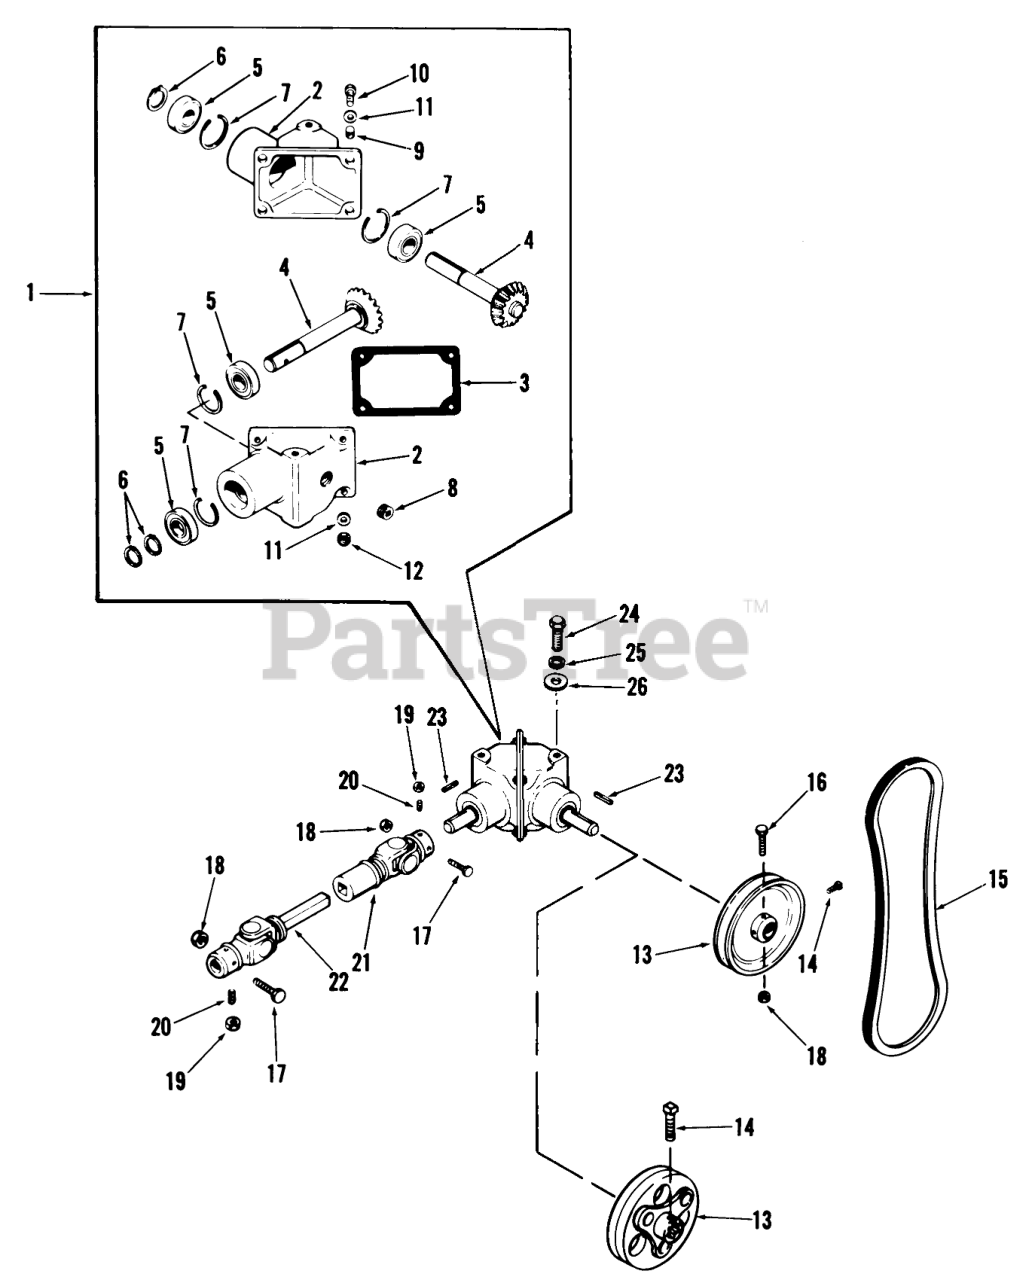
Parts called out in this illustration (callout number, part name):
1	Assembly-Gearbox
2	Gearbox Case Half
3	Gasket
4	Assembly-Shaft & Gear
5	BEARING-GEAR BOX
6	RING-SNAP
7	Ring-Snap
8	PLUG PIPE
9	BUSHING
10	Bolt
11	WASHER 5/16 SAE
12	Keps Nut 5/16-18
13	Flex Coupling
13	Pulley
14	Set Screw 5/16-18 x 3/8
14	Set Screw
15	V-Belt
16	Screw-Hex. Hd.
17	Bolt 1/4-20 x 2
18	Nut
19	Nut
20	Set Screw 3/8-16 x 5/8
21	Slip Assembly-Female End
22	Slip Assy.-Male End
24	BOLT
25	LOCKWASHER
26	WASHER
26	Washer
